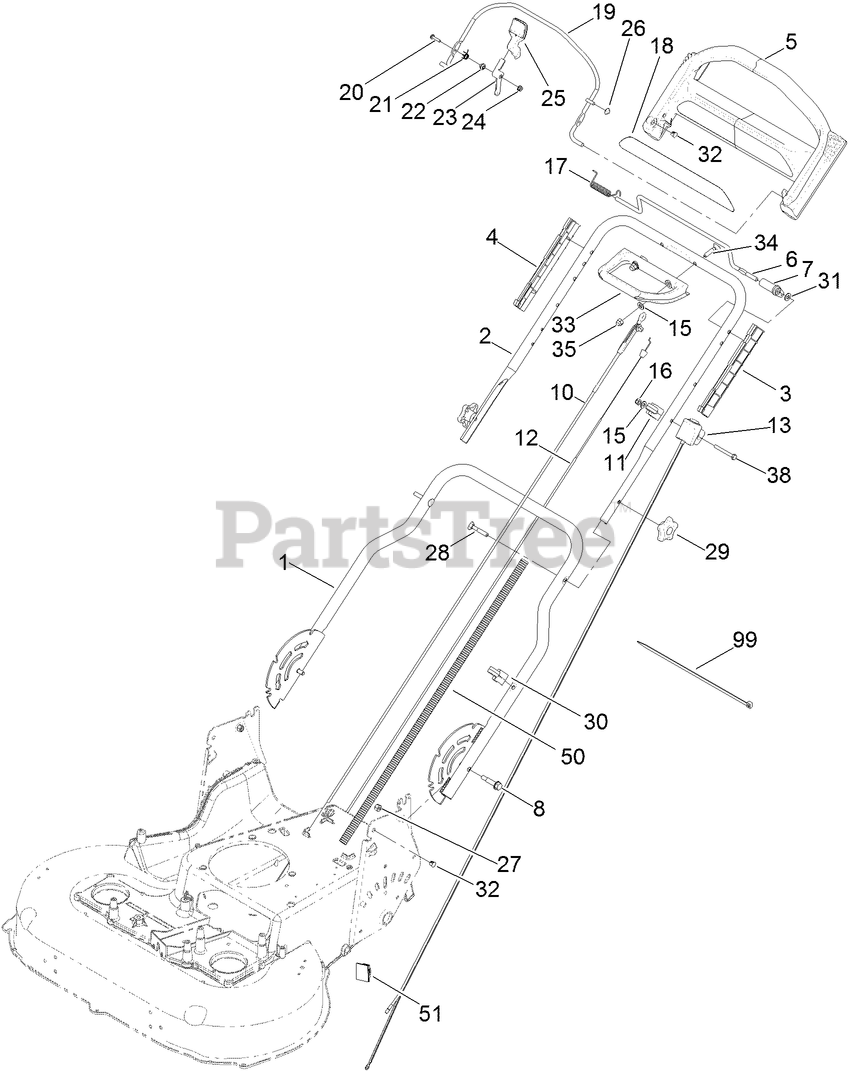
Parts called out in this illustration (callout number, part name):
2	HANDLE-UPPER
3	GUIDE-LH
4	GUIDE-RH
5	HANDLE-CONTROL
7	LEVER-TRACTION
8	BOLT-SHOULDER, HHF
12	CABLE-TRACTION
13	SWITCH HOUSING ASM
15	WASHER-FLAT
16	NUT-LOCK, NI
18	DECAL-HANDLE
19	BAIL-BRAKE
20	SCREW-HWH
21	SPRING-TORSION
22	SPACER
23	LEVER
24	NUT-LOCK, FLANGE
26	NUT-SPEED
27	NUT-LOCK, NI
28	SCREW-HANDLE
29	KNOB-HANDLE
30	GUIDE-CABLE
31	WASHER-PLAIN
32	PLUG-DOME
33	HANDLE-ASSIST, TRACTION
34	SCREW-HANDLE
35	NUT-HEX, NYLON CAP
38	SCREW-HH
50	CONDUIT-CONVOLUTED
51	CLIP-CONDUIT
99	TIE-CABLE
